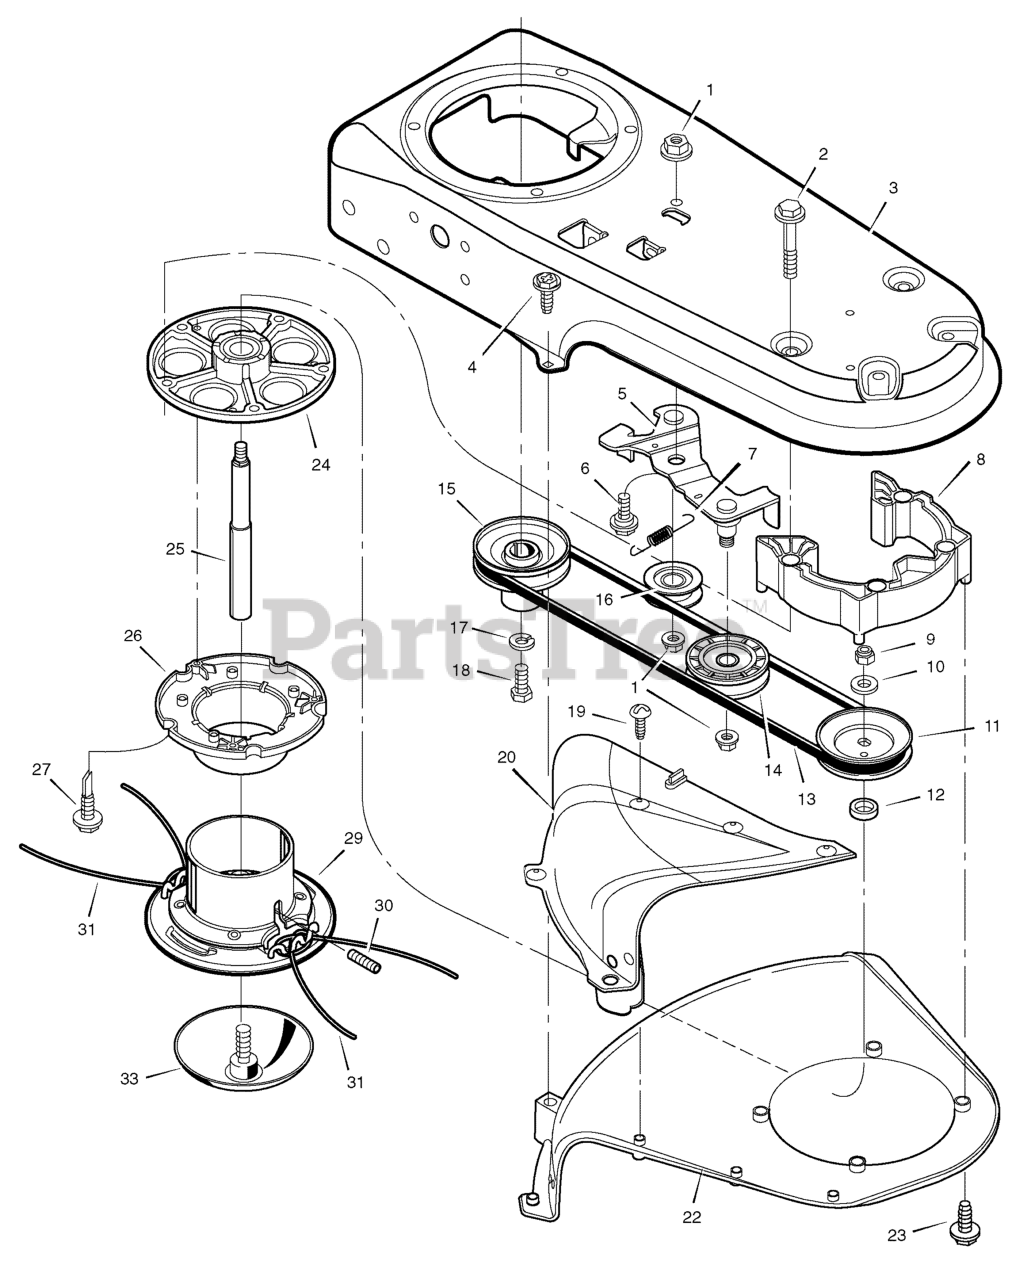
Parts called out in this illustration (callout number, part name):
1	NUT
3	HOUSING, Trimmer
5	IDLER ASSEMBLY
8	SPACER ASSEMBLY
10	WASHER
11	PULLEY, Cutting Head
13	BELT
14	PULLEY, IDLER, V, 1.88
15	PULLEY, Engine
16	PULLEY, Idler
17	LOCKWASHER
20	GUARD ASSEMBLY
22	SHIELD, Trimmer
24	JACKSHAFT HOUSING ASSEMBLY
25	JACKSHAFT
26	WRAP, Upper Weed
29	CUTTING DISC ASSEMBLY
30	SCREW, Set
31	LINE, Cutting
33	GUIDE ASSEMBLY, Metal Height
